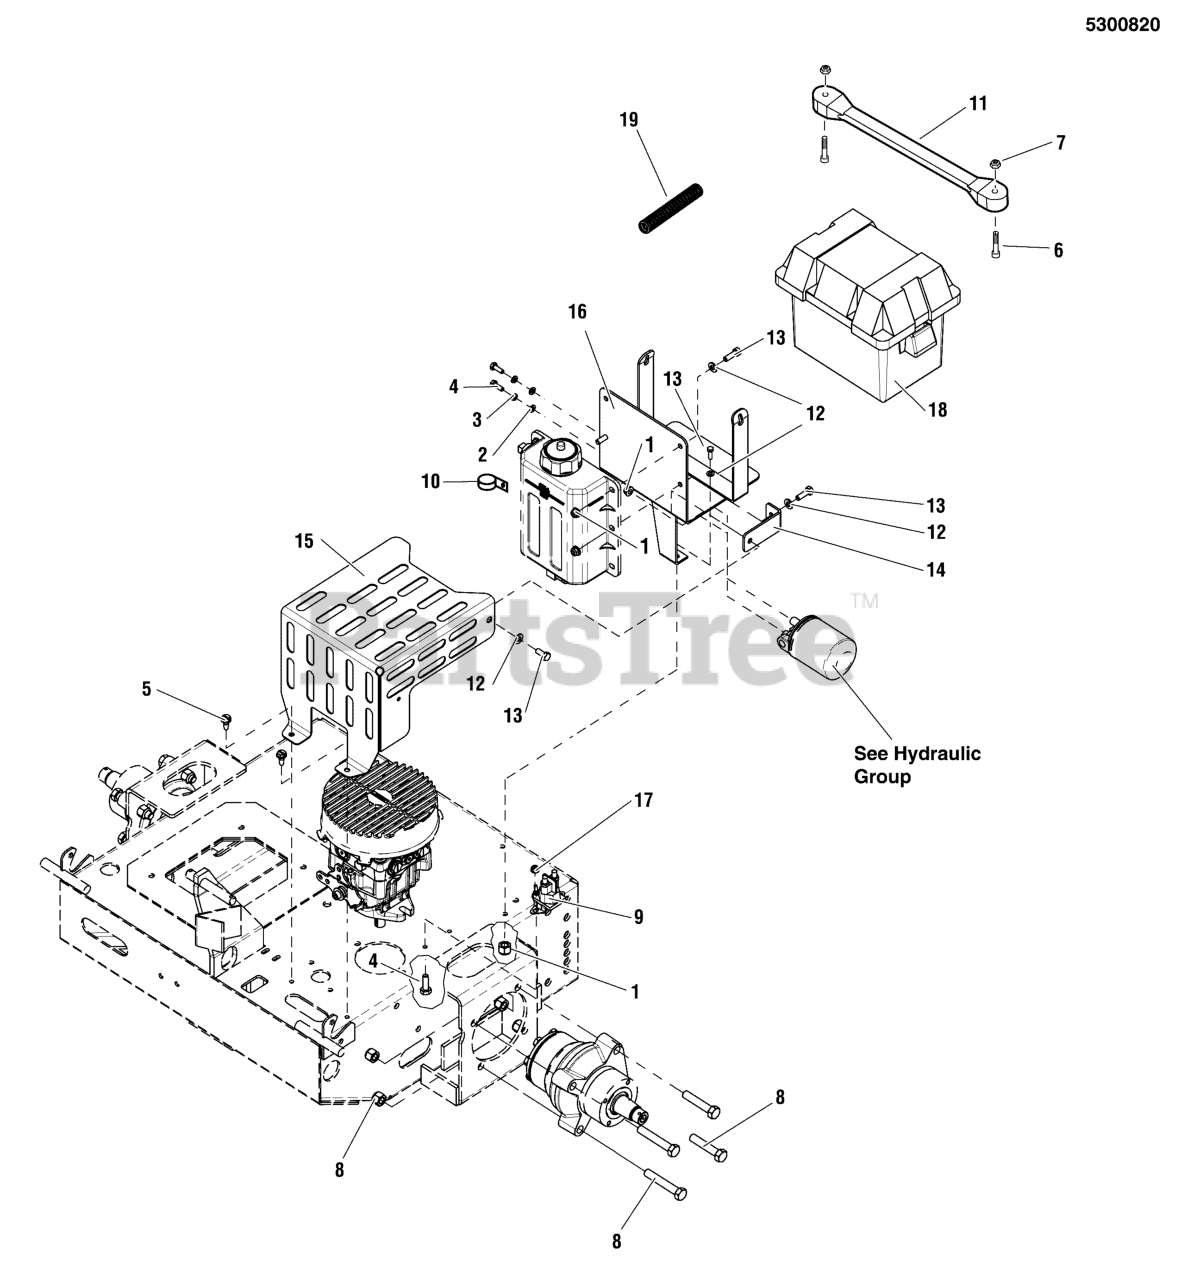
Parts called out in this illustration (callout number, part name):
1	NUT, 5/16-18 HEX NYLOCK FLANGE
2	WASHER, 1/4 SAE
3	WASHER, 1/4 LOCK
4	BOLT, 1/4-20 X 3/4" GD5 YZ
5	BOLT, 5/16-18 X 3/4", SELF-TAPPING
6	SCREW, #10-24 X 1 RS, CZ
7	NUT, #10-24 HEX NYLON LOCK
9	SOLENOID-4 POLE 12 VOLT DC (TROMBETTA)
10	CLAMP, HOSE, 1.000 DIA
11	STRAP, RUBBER
12	WASHER, 5/16" SAE
13	BOLT, 5/16-18 X 1" GD5 YZ
14	BRACKET, MUFFLER - RED
15	PLATE, PUMP COVER - RED
16	WELD, BATTERY BOX & RES. MOUNT - RED
17	NUT, 1/4-20 HEX NYLOCK FLANGE
18	BATTERY BOX, W/ DRAIN HOLE
19	WIRE LOOM, 1/2 ID X 10 IN
